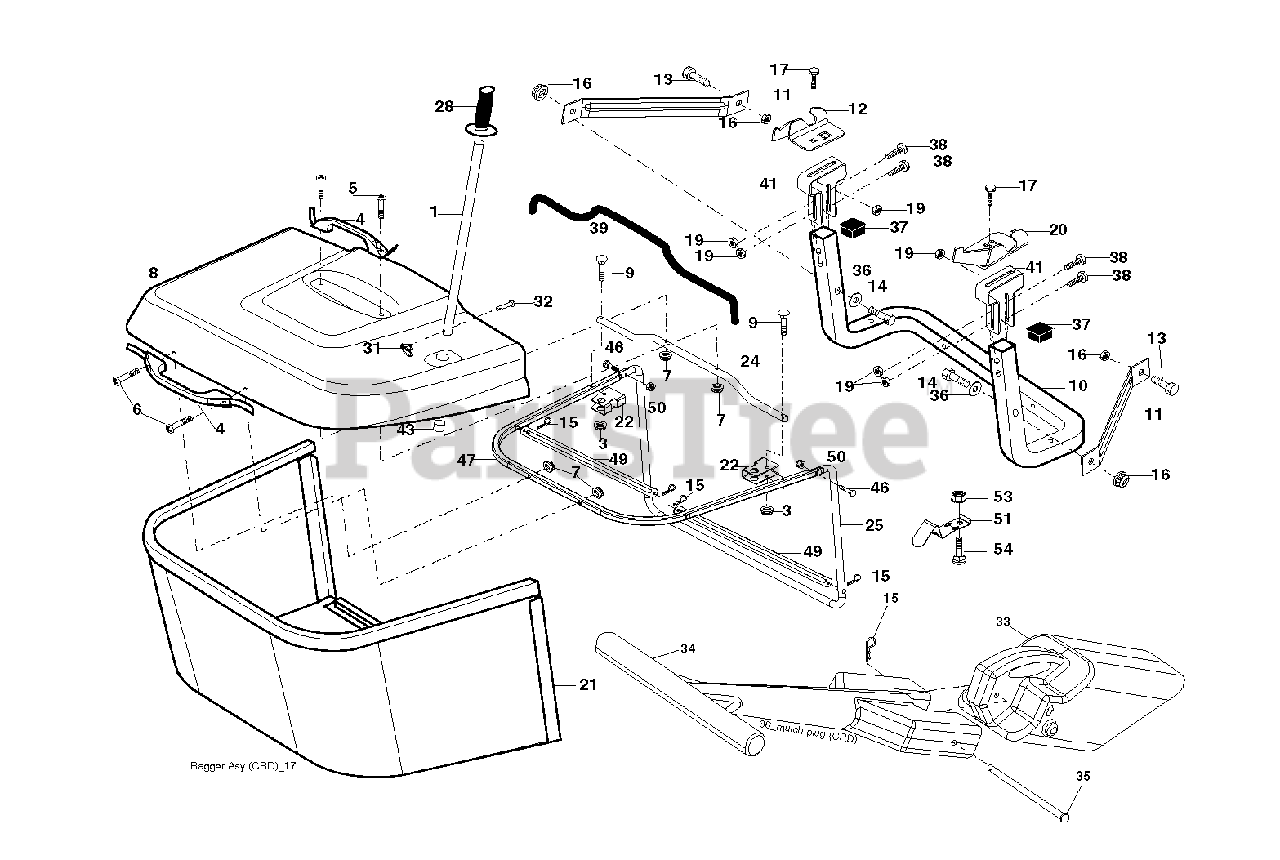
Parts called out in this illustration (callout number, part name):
1	TUBE.PNT.HDL.BAGGER.
3	NUT T
5	SCREW.PAN.HEAD
8	COVER.PNT.BGR.CRD.WSLOTS.MS667
11	BRACKET
14	BOLT-HEX EAK
15	RETAINER-SPRNG RB
16	NUT LOCK FLG 3/8-16 UNC
17	BOLT
19	NUT LOCK HEX FLANGE 5/16-18
20	BRKT.PIVOT.RH.CRD
21	BAGGER.ASM.CRD.2007
22	BRACKET.BAGGER.SD.
24	TUBE
28	GRIP.HANDLE.BLACK
31	RETAINER CLIP
32	RIVET,DRILLED
33	MULCHING.PLUG.1078.CRD.NON-TEX
35	PIN
38	BOLT.5/16-18X2.5
39	SEAL.BAGGER.CRD
41	BRACKET.BAGGER.SD.
43	PLUG, TUBING END
46	BOLT.CARRIAGE.5/16-18
50	NUT.71038.31-18.HEX.NYLOCK
53	NUT
54	BOLT
